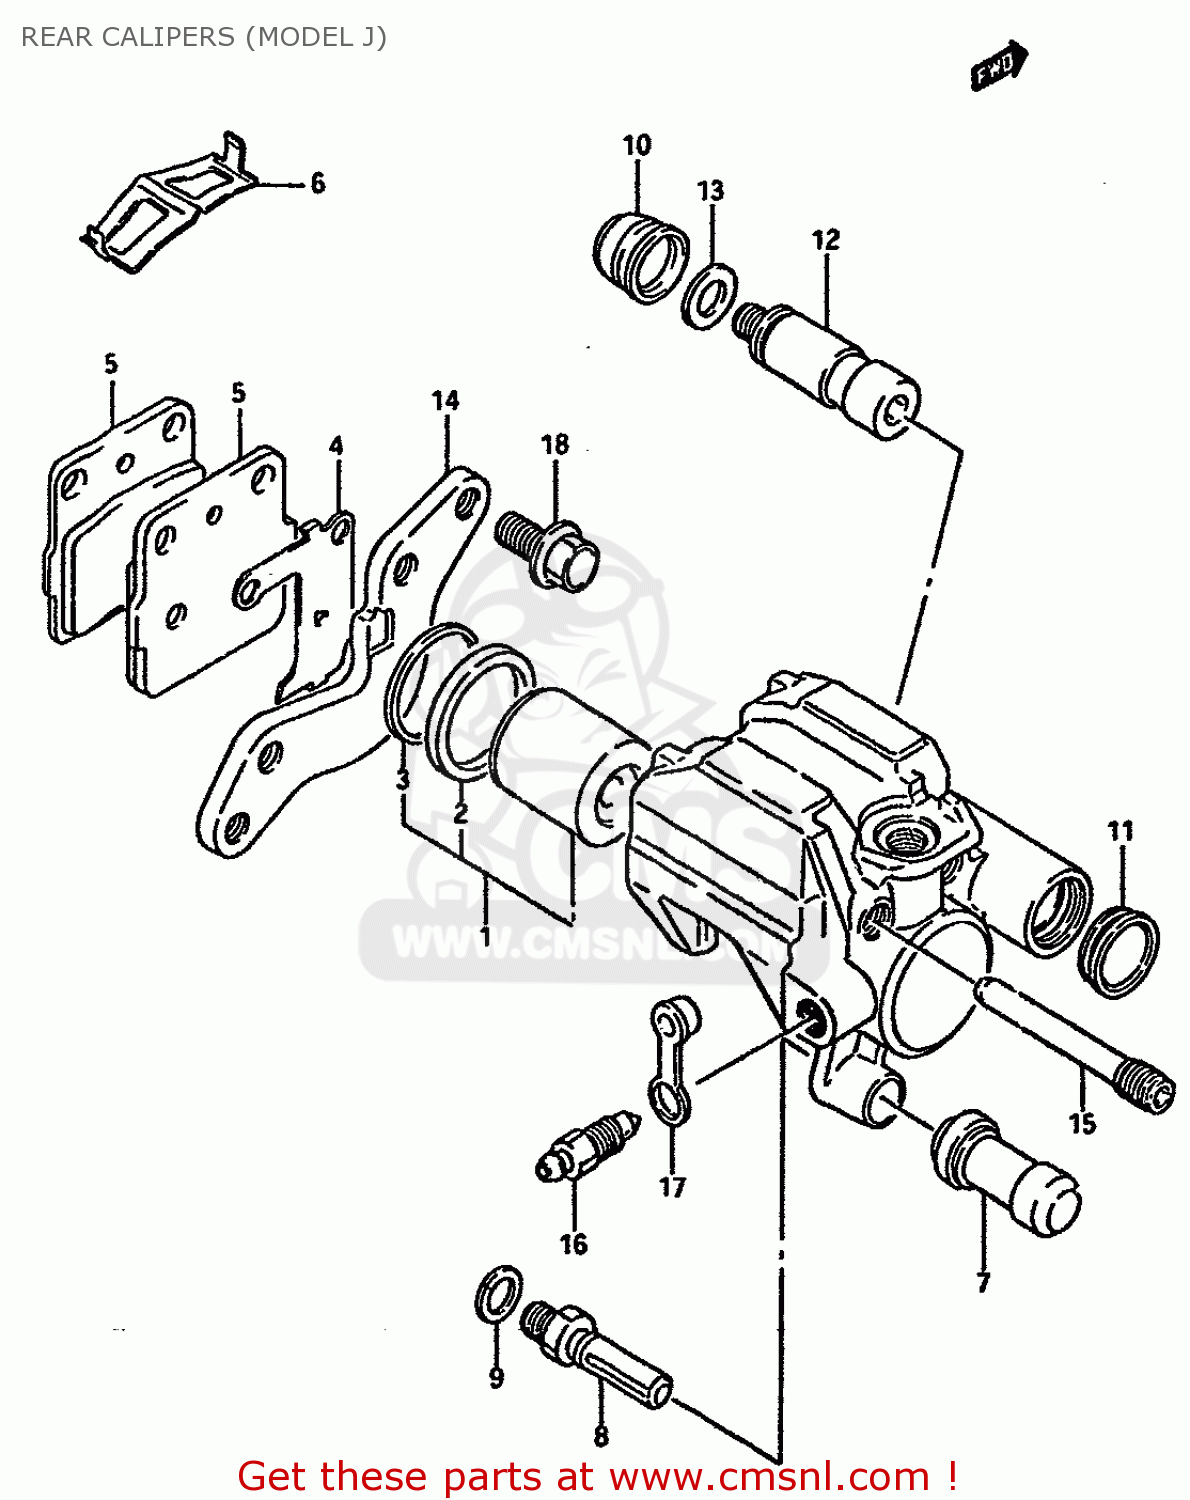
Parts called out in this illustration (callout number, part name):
1	PISTON SET
2	SEAL,PISTON
3	SEAL,DUST
4	SHIM
5	PAD (NAS)
6	SPRING,PAD
7	BOOT
8	BOLT,PIN
9	WASHER,WAVE
10	BOOT,PIN
11	DUST SEAL
12	PIN,SLIDE
13	SPRING,FRICTION
14	BRACKET
15	PIN
16	BLEEDER
17	CAP,BLEEDER
18	BOLT L:21
